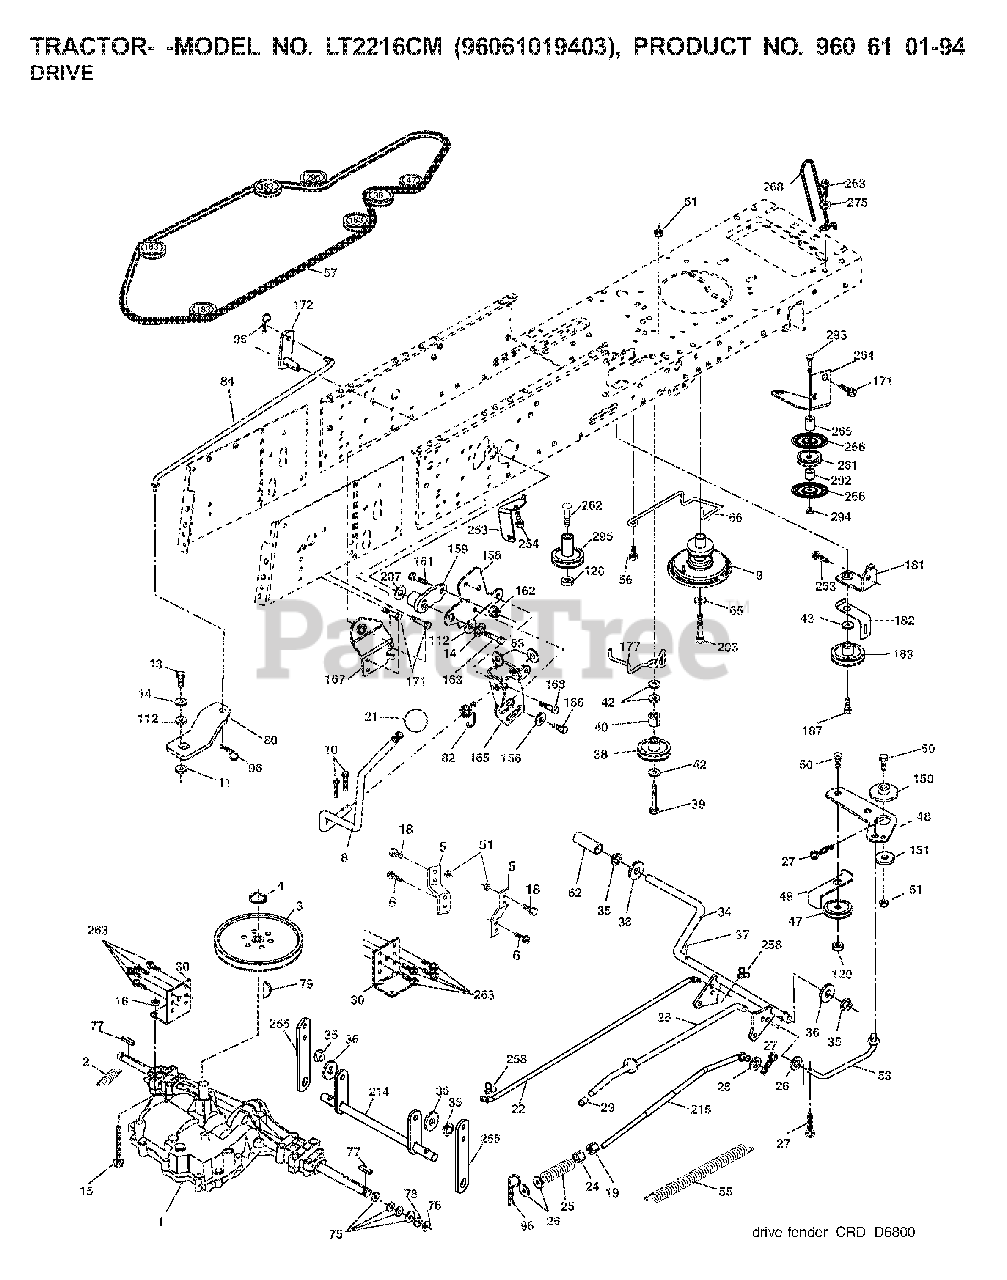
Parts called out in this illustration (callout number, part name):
2	SPRING,BRAKE RETURN
4	RETAINING RING LT
5	STRAP TORQUE
6	SCREW 5/16"
8	ROD SHIFT FENDER ADJUST LT
10	PIN COTTER
11	WASH-SHFT PLT LT
13	BOLT 1/4-28X3/4
14	LOCKWASHER
15	BOLT HEX 5/16-18 GR 5
16	NUT.71038.31-18.HEX.NYLOCK
19	NUT
21	KNOB.DUCKHEAD.1/2
24	NUT
25	SPRING ROD LT
27	COTTER PIN
28	ROD, PARKING BRAKE
29	PLUNGER CAP
30	BRKT, MOUNT TRNSAXLE
34	SHAFT, FOOT PEDAL
35	BEARING.NYLON
36	WASHER LT
37	DRIVE PIN
38	PULLEY.FLAT
42	WASHER
47	IDLER PULLEY
48	BELLCRANK, CLUTCH
49	RETAIN BELT
50	BOLT.3/8-16X1.50
51	LOCKNUT
53	LINK.CLUTCH.7.66.2005
55	SPRING, RETURN LT
56	SCREW.3/8-16
62	PEDAL COVER T
65	LOCKWASHER
66	KEEPER BELT ENGINE
76	E-RING LT
77	SQUARE KEY
80	ARM SHIFT
82	SHIFT SPRING
83	WASHER
96	RETAINER M
112	WASHER LT
120	NUT LOCK FLG 3/8-16 UNC
150	BUSHING.BELLCRANK.GRD.DR
151	WASHER 12/32X2X10GA
156	WASHER.SRRTD.5/16
158	BRACKET
159	HUB.SHIFT
161	BOLT
162	NUT.CROWNLOCK.1/4
165	RP BRACKET
167	BRACKET
168	BOLT.SHOULDER.5/16-18X
187	BOLT.5/16-18X1.25
207	WASHER NYL
254	SCREW 3/8-16X1
258	CLIP RETAINER
261	FLAT IDLER PULLEY
263	SCREW, 3/8-16X3/4
275	WASHER
294	NUT, HEX 3/8-16
295	PULLEY IDLER COMPOSITE
